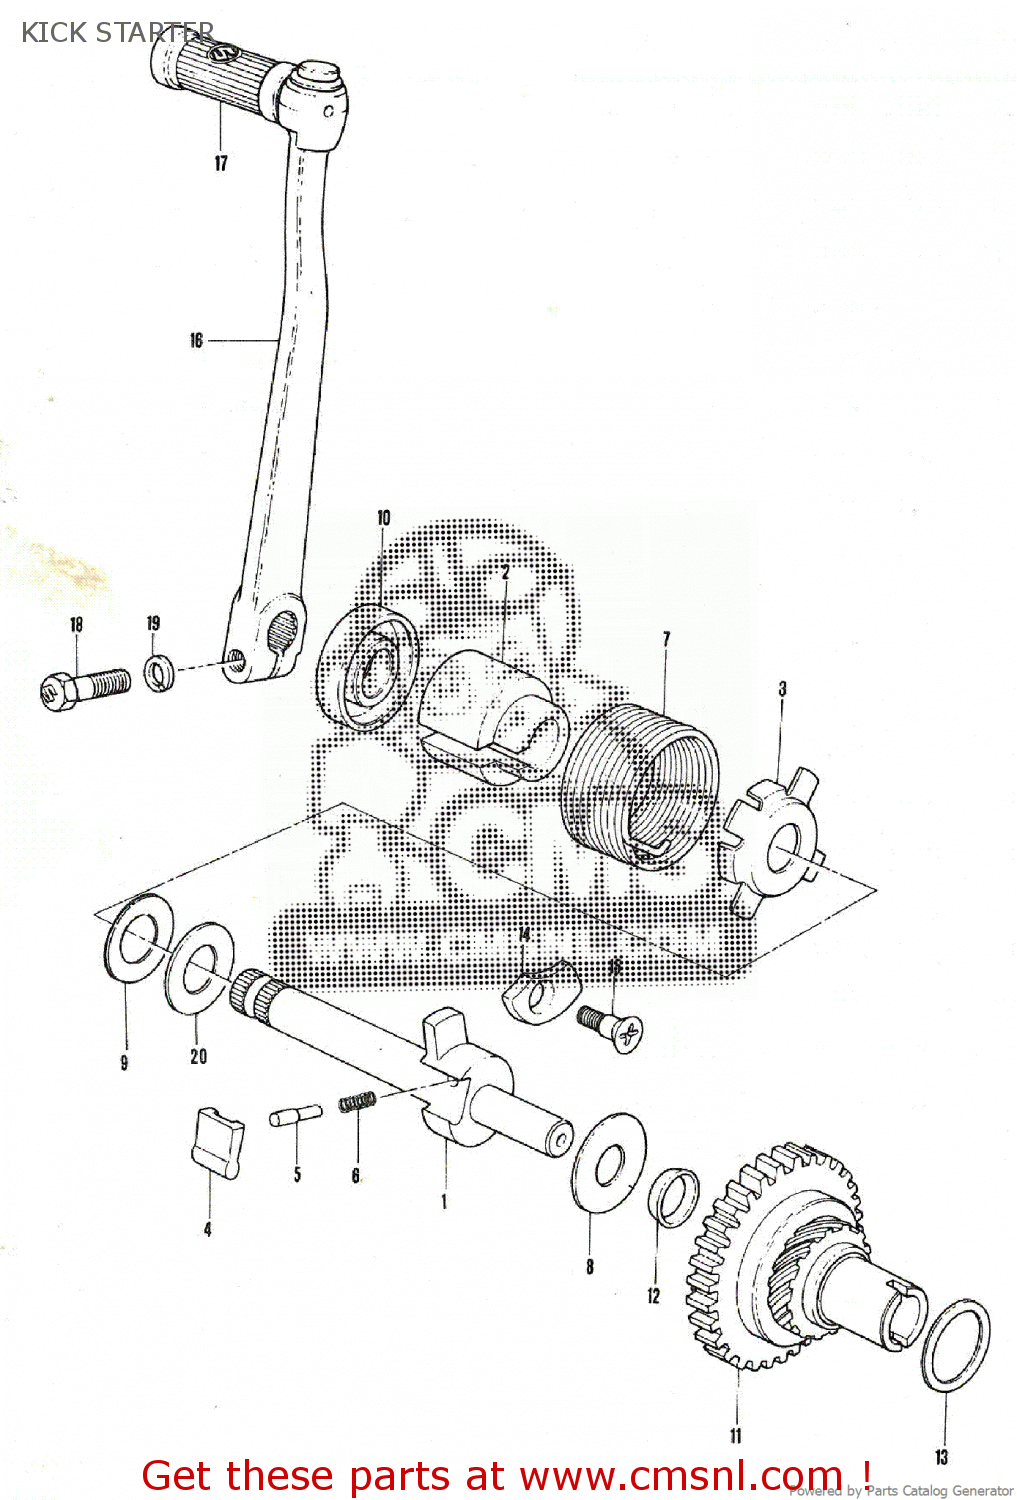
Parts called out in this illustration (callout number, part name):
1	SHAFT,KICK STARTER
2	GUIDE,KICK SHAFT SPRING
3	HOLDER,KICK SHAFT SPRING
4	PAWL,KICK STARTER
5	PIN(5X15.5)
6	SPRING
7	SPRING
8	WASHER
9	WASHER(16X30X0.5)
10	SEAL,OIL(16X30X8)
11	GEAR,KICK STARTER DRIVE
12	OIL SEAL
13	WASHER
14	LIFTER,KICK STARTER PAWL
15	SCREW(6X19)
16	LEVER ASSEMBLY,KICK STARTER
17	RUBBER,KICK STARTER PEDAL
18	BOLT
19	LOCK WASHER
20	WASHER
